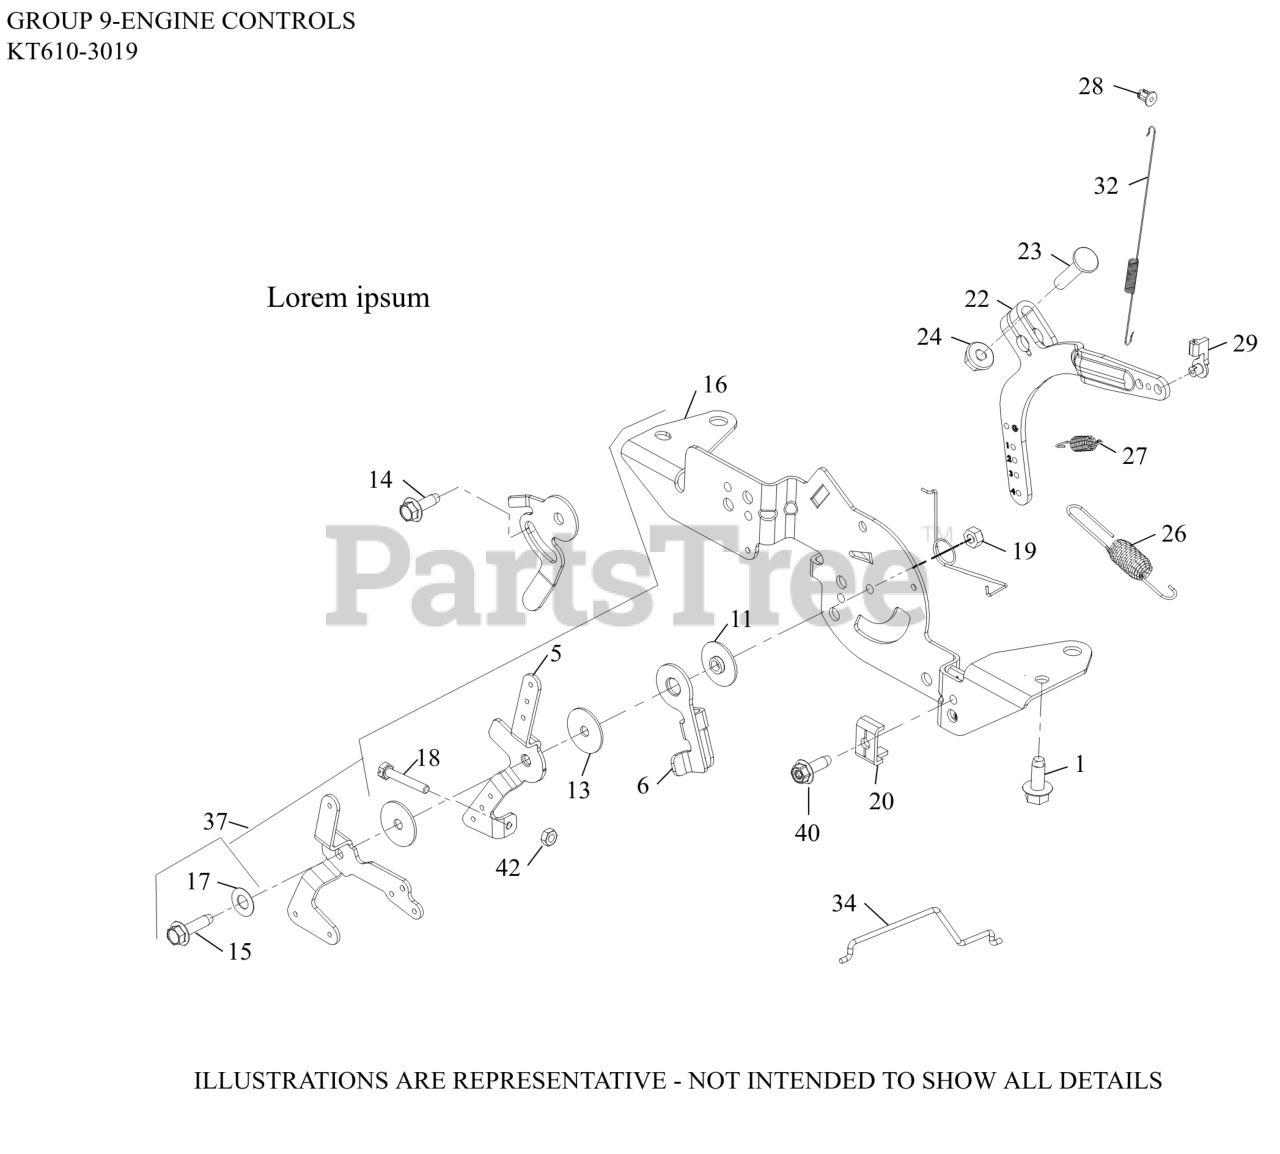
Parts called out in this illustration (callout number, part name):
1	SCREW, THREAD FORMING
5	LEVER, THROTTLE CONTROL
6	LEVER, THROTTLE ACTUATOR
11	SPACER, CONTROL ASSEMBLY
13	WASHER, FLAT 5 MM
14	SCREW, THREAD FORMING
15	SCREW, THD FRM-USE 25 086 473-S
16	BRACKET, SPEED CONTROL
17	WASHER, SPRING 1/4"
18	SCREW, SLT HD CAP M4X0.7X25
19	NUT, LOCK M5X.8
20	CLAMP, CABLE CABLE
22	LEVER, GOVERNOR - (#2409069S)
23	BOLT, RD HD SQ NECK M6X1.0X25
24	NUT, FLG M6X1.0
26	SPRING, GOVERNOR (ORANGE)
27	SPRING, GOVERNED IDLE
28	BUSHING, LINKAGE RETAINING
29	BUSHING, THROTTLE LINKAGE
32	SPRING, LINKAGE
34	LINKAGE, THROTTLE
37	SPEED CONTROL, ASSEMBLY
40	SCREW, THREAD FORMING
42	NUT, M4X0.7
